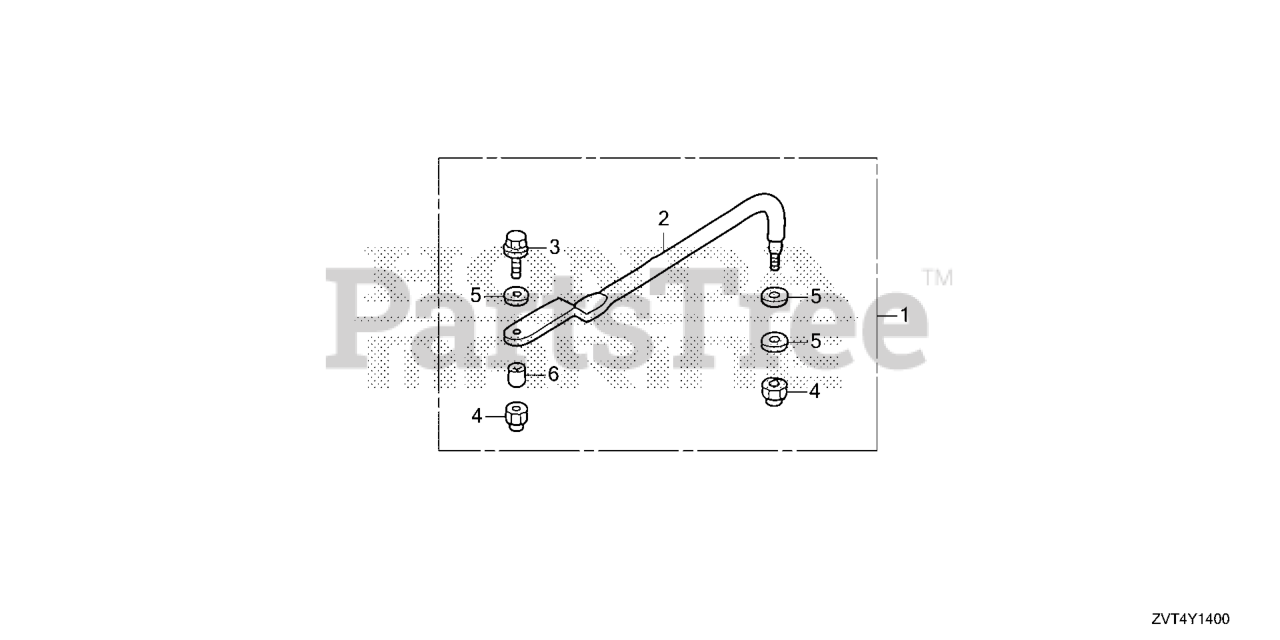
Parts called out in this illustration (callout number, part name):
1	ROD KIT, STEERING
2	ROD, STEERING
3	BOLT (3/8-24UNF)
4	NUT, SELF-LOCK (3/8-24UNF)
5	WASHER (10MM)
6	COLLAR, STEERING ROD
